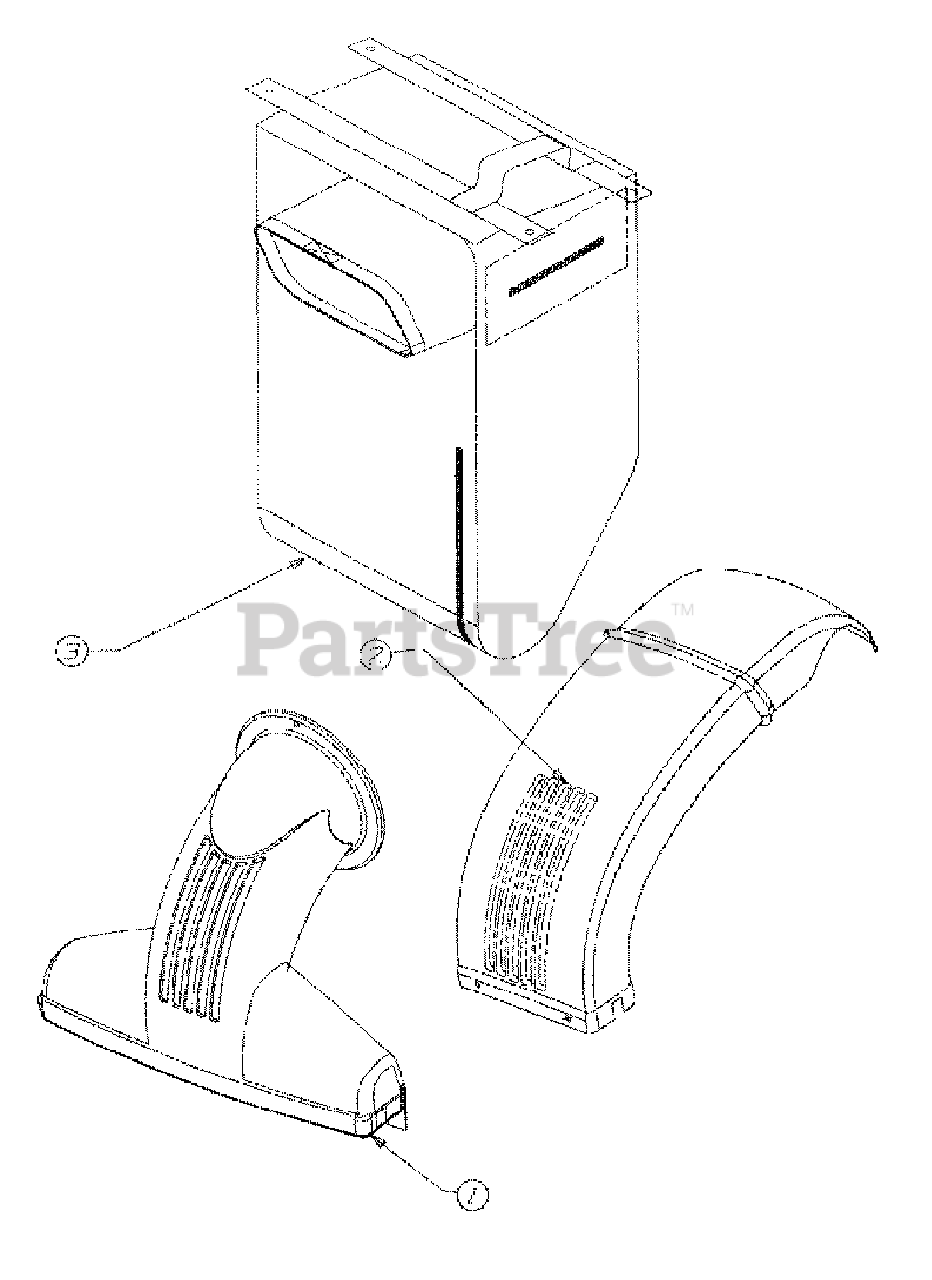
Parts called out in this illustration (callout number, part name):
1	NOZZLE ASS'Y.-VACUUM
2	CHUTE-DISCHARGE
3	BAG-VACUUM
